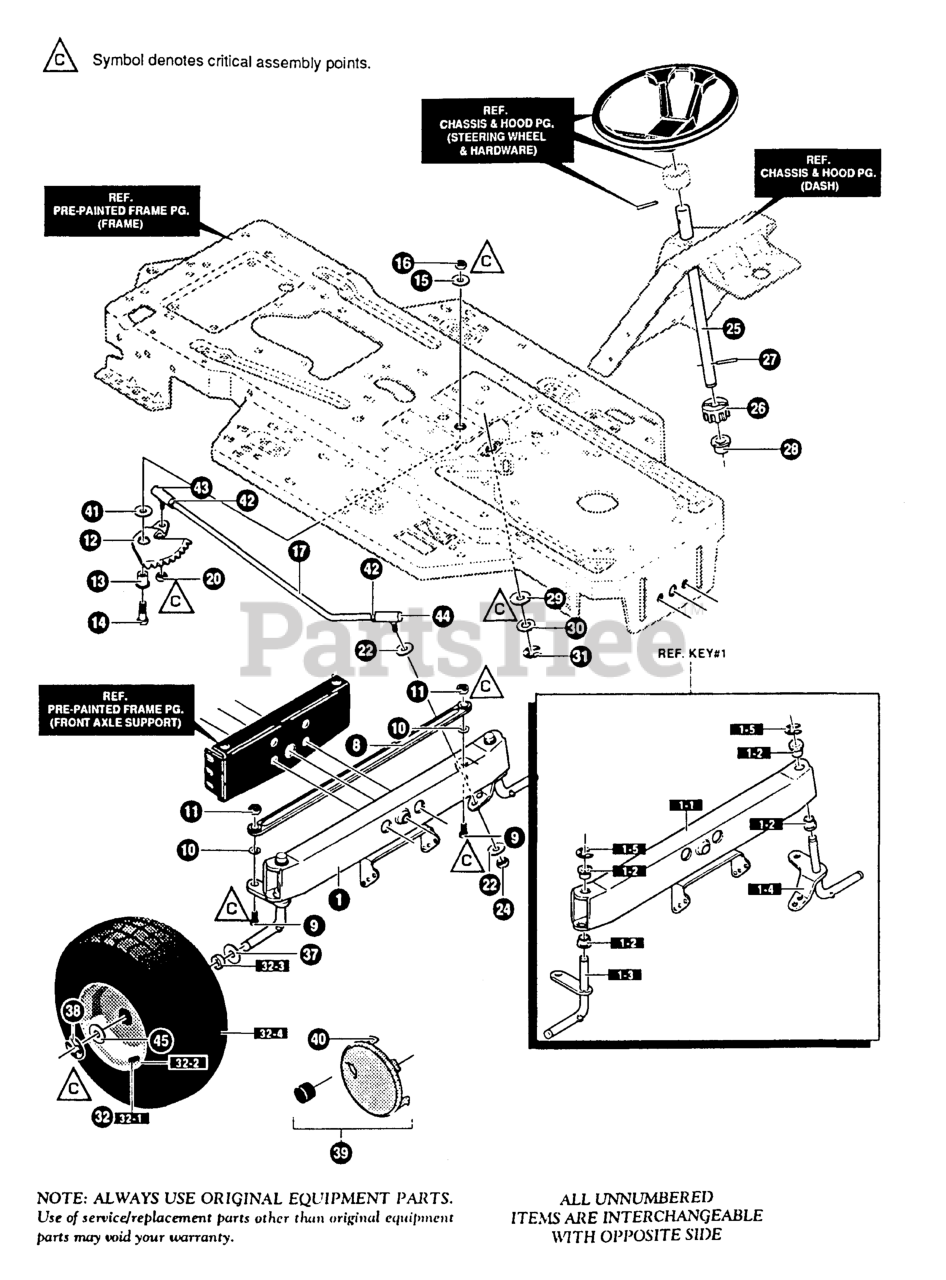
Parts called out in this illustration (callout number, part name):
1	AXLE, FRONT ASSEMBLY
1-1	ASSEMBLY FRONT AXLE
1-2	SPINDLE BEARING
1-3	ASSMBLY, SPINDLE, RH
1-4	ASSEMBLY, SPINDLE, LH
1-5	RING, RETEX
8	TIE ROD ASSEMBLY
9	SCREW, 3/8-16 X 1.75
10	WASHER, .393 X .68 X. 10
11	NUT, 3/8-16
12	SECTOR, STEERING
13	BEARING, FLANGE
14	SCREW, 1/2-13 X 1.50
15	WASHER, FLAT .515 X 1.38 X .119
16	NUT, 1/2-13
17	STEERING LINK
20	NUT, 3/8-14
22	WASHER, FLAT .391 X 1.00 X. 125
24	NUT, 3/8-24
25	SHAFT, STEERING
26	PINION, STEERING
27	PIN, DOWEL
28	BEARING, FLANGE
29	WASHER, FORMED
30	WASHER, FLAT .765 x 1.25 x .042
31	RING, RETEX
32	TIRE & RIM ASSEMBLY, PU 15 X 6.0 X 6
32-1	VALVE STEM
32-2	RIM, WHEEL
32-3	BEARING
32-4	TIRE, 15 X 6-6
37	WASHER, FLAT .755 X 1.31 X .075
38	RING, RETEX
39	HUB CAP, 6"
40	CLIP, HUBCAP
41	WASHER, FLAT .520 X 1.25 X .209
42	NUT, 3/8-24
43	BALL JOINT, 3/8 THD SHORT STUD
44	BALL JOINT, 3/8 THD LONG STUD
45	WASHER, FLAT .755 X 1.53 X .07
